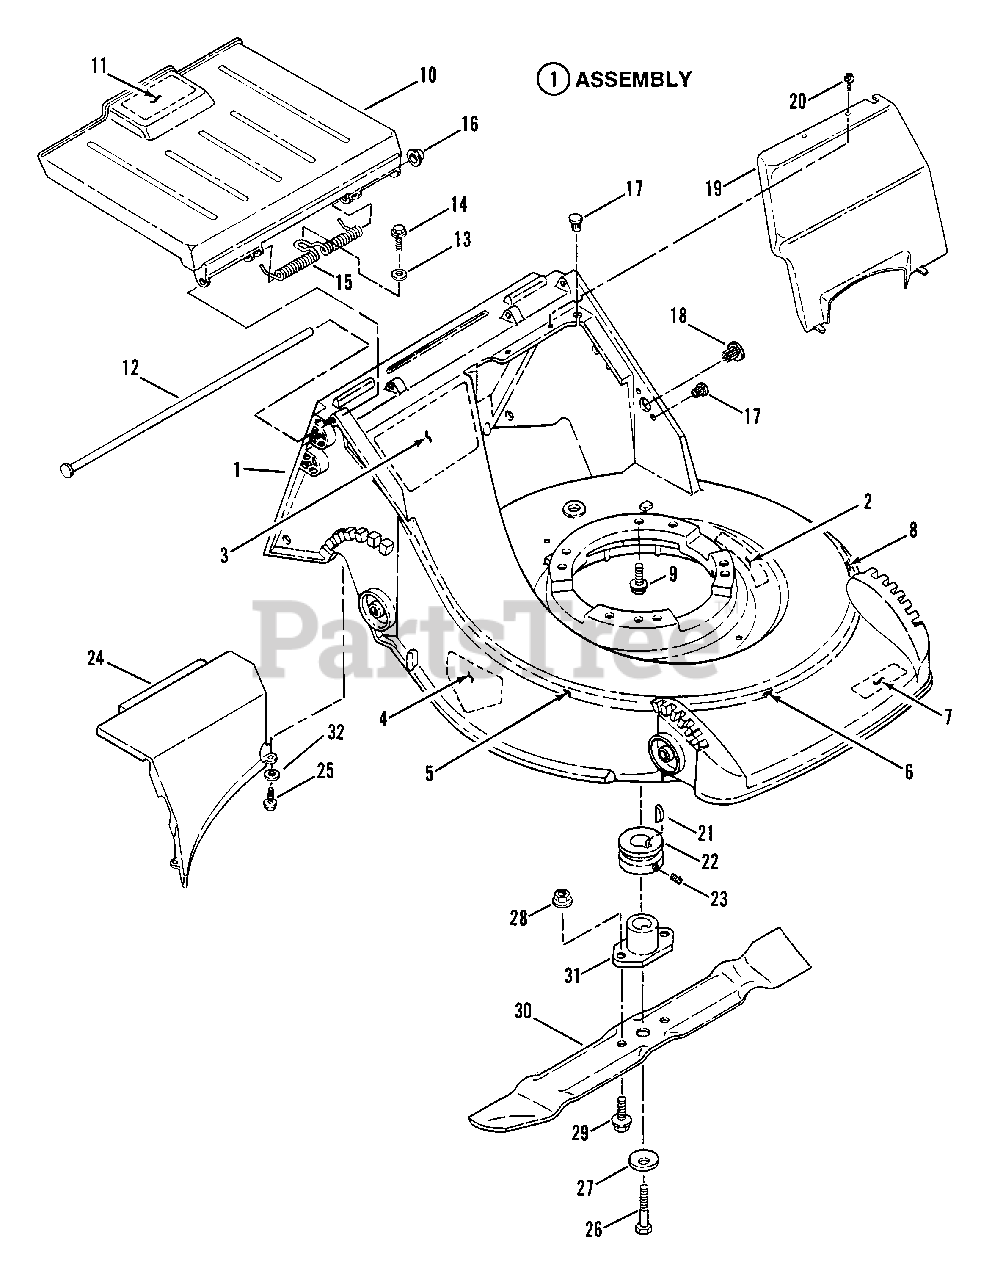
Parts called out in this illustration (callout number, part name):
1	ASSEMBLY, Deck & Decals
2	DECAL, WARNING
3	DECAL, Mulching Convertible
4	DECAL, DANGER
5	DECAL, Stripe (Right Hand Side)
6	DECAL, Stripe (Front)
7	DECAL, SNAPPER, Mulching Convertible
8	DECAL, Stripe (Left Hand Side)
9	BOLT, 3/8-16 x 1" Self-Tapping (Engine Mounting)
10	ASSEMBLY, Door/Decal
11	DECAL, Quick Change Convertible
12	ROD, Door Hinge
13	WASHER, 1/4 Flat
14	SCREW, #10-16 x 5/8" Self-Tapping
15	SPRING, Torsion
16	NUT, 5/16 Push
17	PLUG, 1/4"
18	PLUG
19	COVER, Drive
20	SCREW, #10-24 x 1/2" Hex Washer Self-Tap (Torx)
21	KEY, #605 Woodruff
22	PULLEY, Engine
23	SCREW, 5/16-18 x 5/16" Hex Socket Set
24	BAFFLE, Rear
25	SCREW, 1/4-20 x 5/8" Truss Head (Torx)
26	SCREW, 3/8-24 x 1-3/4" Hex Head Cap (Gr. 5)
27	WASHER, 3/8 Split Lock
28	NUT, 3/8-16 Hex Top Lock (Nyloc)
29	BOLT, 3/8-16 x 1-1/4" Hex Head Cap
30	BLADE, 21" Cutter
31	HUB, Blade Drive
32	WASHER, 9/32" Flat
